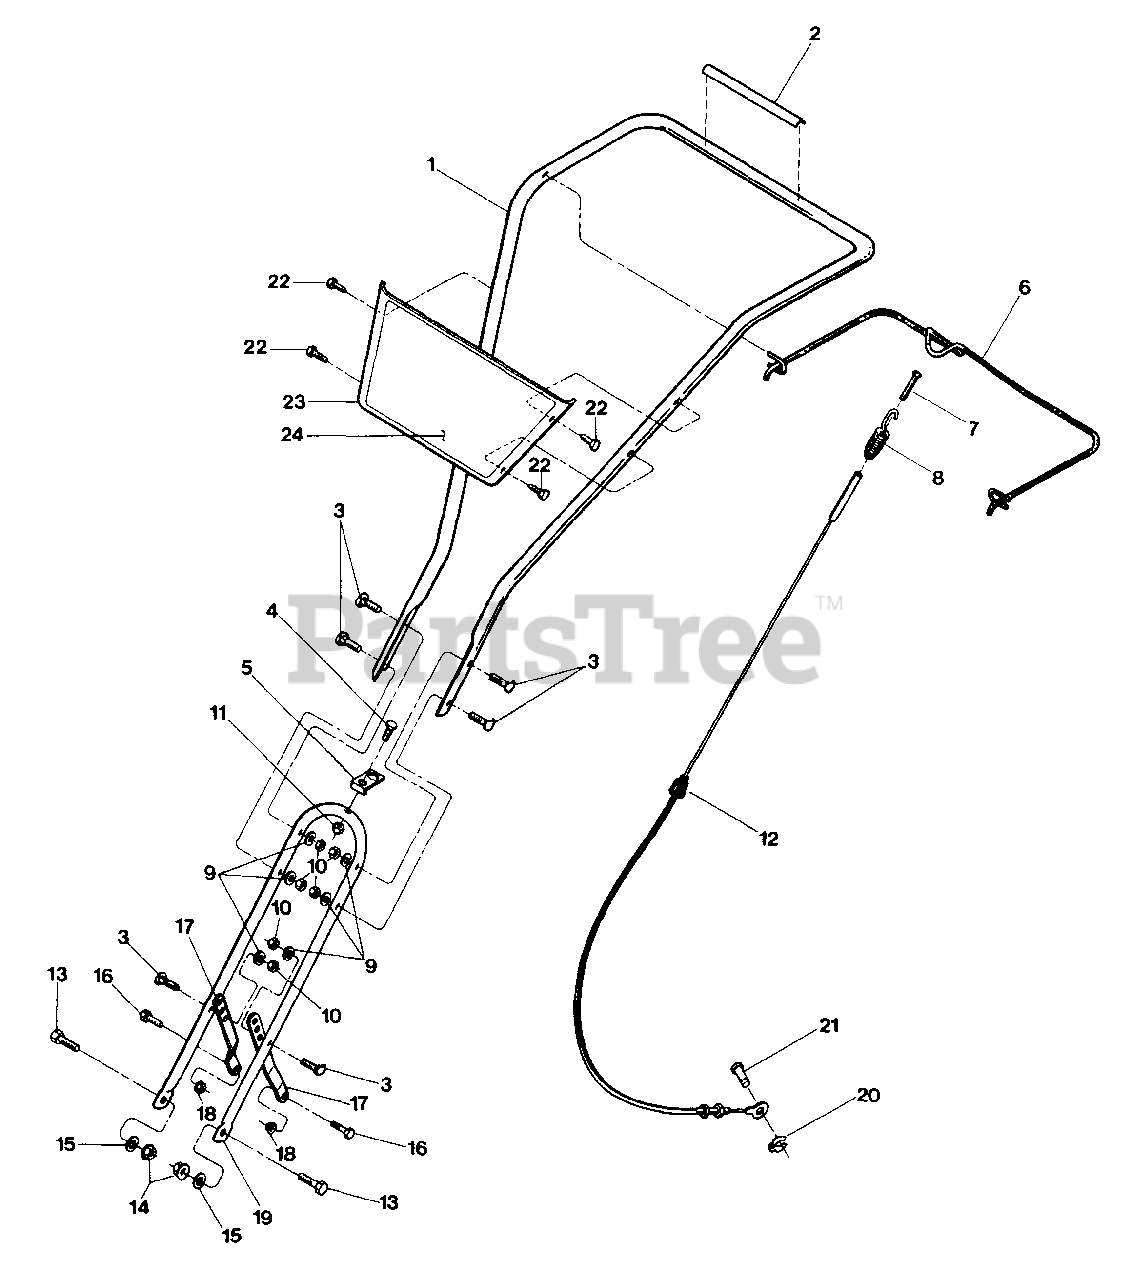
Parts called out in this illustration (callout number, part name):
1	Handlebar, Upper
2	Decal-Forward Clutch Bail
3	Bolt-Curved Hd., 5/16-18 x 1-1/2"
4	Bolt-Hex Hd, 1/4-20 x 1-1/4"
5	Bracket, Cable
6	Bail-Forward Clutch
7	Screw, 10-24 x 2"
8	Spring-Forward Clutch
9	Lockwasher-5/16"
10	Nut-Hex Hd, 5/16-18
11	Nut-Hex Hd., Lock, 1/4-20
12	Cable
13	Bolt-Hex Hd, 3/8-16 x 3/4"
14	Locknut-Hex Hd, 3/8-16
15	Washer-Flat, 3/8
16	Bolt-Hex Hd, 5/16-18 x 3"
17	Support, Handlebar
18	Locknut-Hex Hd, 5/16-18
19	Handlebar, Lower
20	Klip Ring
21	Clevis Pin
22	Screw-1/4-20 x 1/2" Self-Tapping Hex Head
23	Graphics Panel
24	Decal-Troy-Bilt Tuffy
